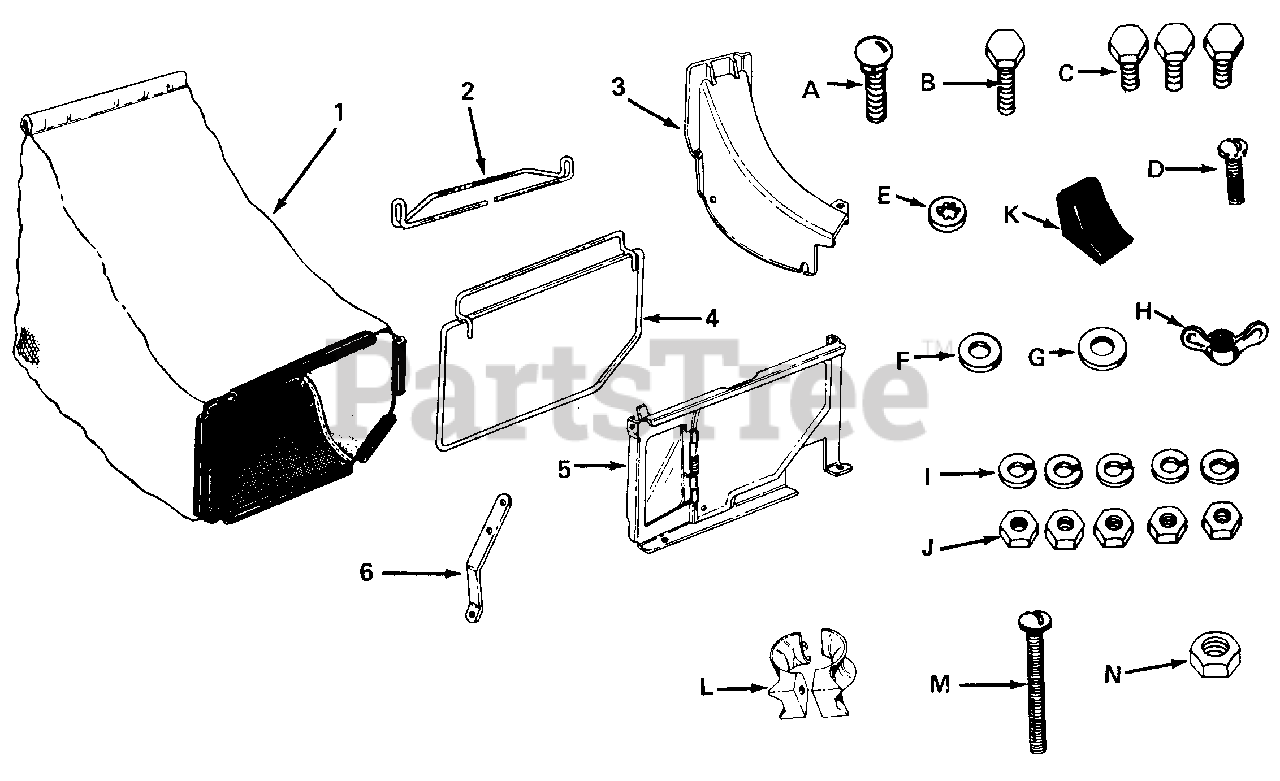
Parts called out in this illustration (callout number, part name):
1	Grass Bag
2	Grass Catcher Handle
3	Top Discharge Chute
4	Front Catcher Frame
5	Top Catcher Panel
6	Panel Support Bracket
A	Carriage Bolt 1/4-20 x 5/8" Lg.*
B	Hex Bolt 1/4-20 x 5/8" Lg.*
C	Hex Bolt 1/4-20 x 1/2" Lg.*
D	Truss Machine Screw 1/4-20 x 1/2" Lg.*
E	Bolt Retainer
F	Flat Washer 5/16" I.D. x 5/8" O.D.
G	Flat Washer 1/4" I.D. x 5/8" O.D.
H	Wing Nut 1/4-20Thread
I	LockWasher 1/4" I.D.*
J	Hex Nut 1/4-20 Thread*
K	Door Grip
L	Rope Guide Half
M	Truss Machine Screw 1/4-20 x 1-1/2" Lg.*
N	Hex Nut 5/16-18Thread*
